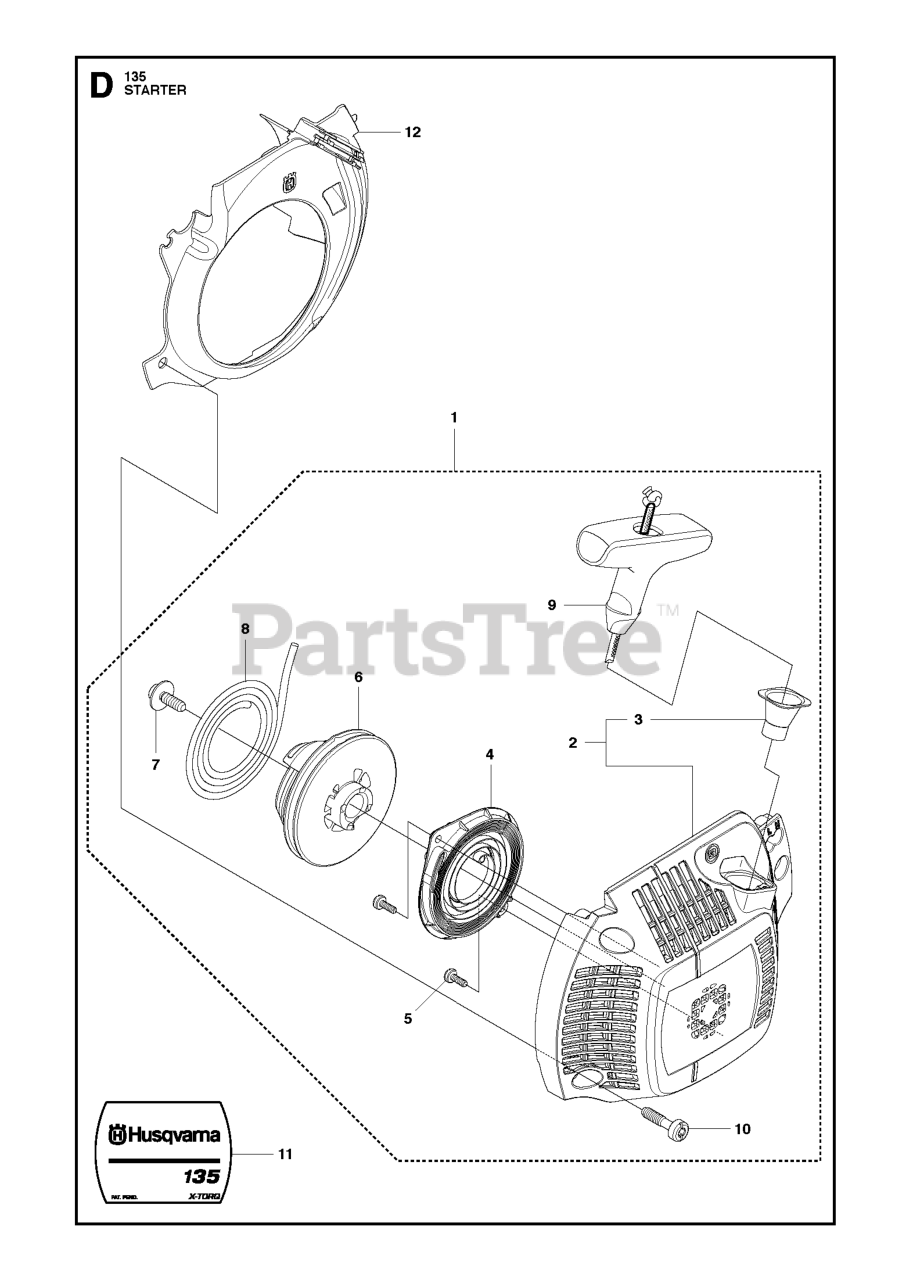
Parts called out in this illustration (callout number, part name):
1	STARTER ASSY
2	HOUSING STARTER
3	SLEEVE
4	SPRING CASSETTE ASSY
5	SCREW
6	STARTER PULLEY
7	SCREW
8	STARTER ROPE
9	HANDLE
10	SCREW
11	LABEL STARTER
12	COOLING AIR CONDUCTOR
